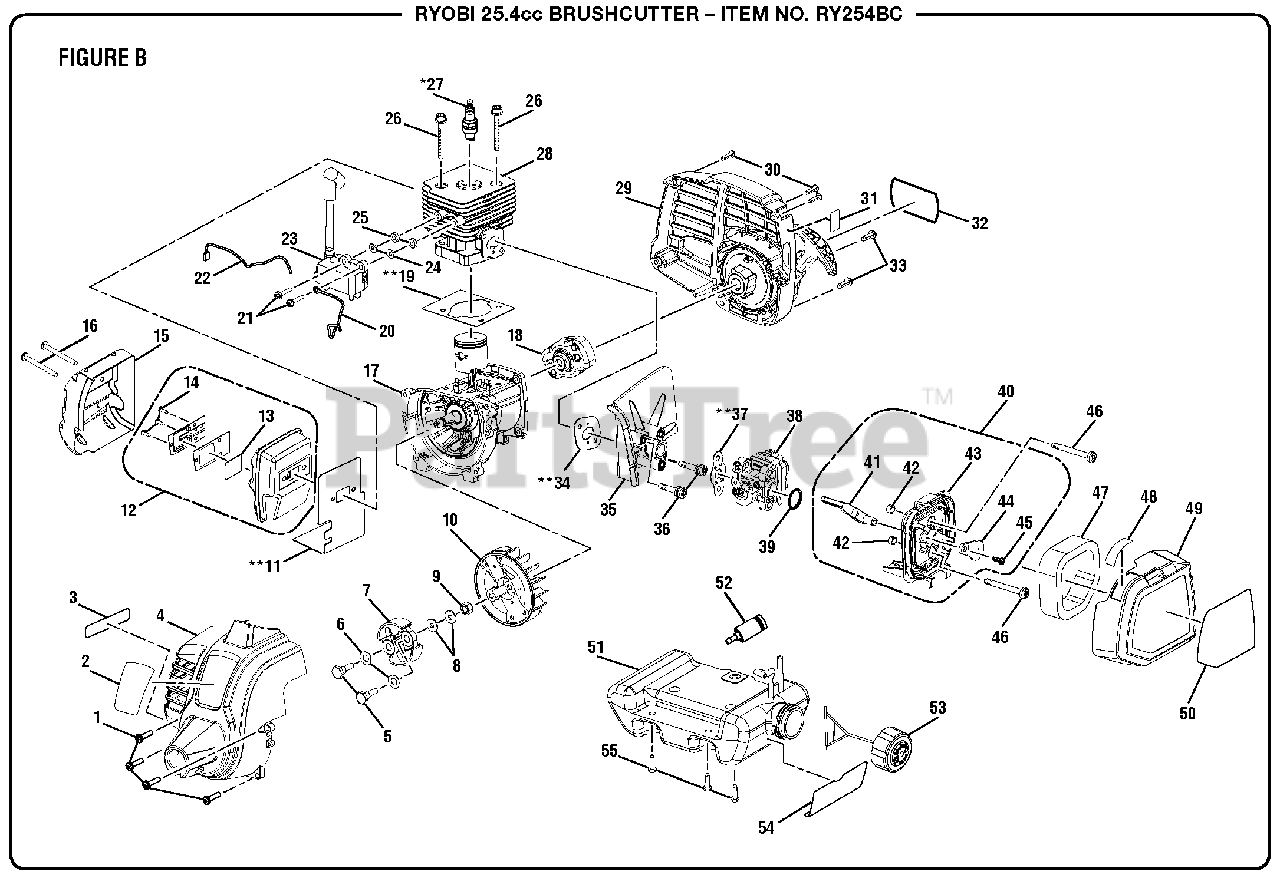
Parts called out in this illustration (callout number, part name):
1	Screw w/Washer (M5 x 20 mm, T20 Torx Pan Hd.)
2	Logo Label (Front)
3	Combustion Warning Label
4	Front Housing Assembly
5	Clutch Shoulder Bolt (M6 x 22.5 mm, Hex Hd.)
6	Curved Washer
7	Clutch Assembly
8	Washer (ID6 x OD15 x 1.2t)
9	Flywheel Nut
11	Muffler Gasket
12	Muffler Assembly
13	Screen
14	Screw (6-20 x 1/4 in., T20 Torx Pan Hd.)
15	Heat Shield
16	Screw (M5 x 50 mm, T25 Torx Pan Hd.)
17	Crankcase Assembly
18	Starter Cup
19	Gasket
20	Lead Wire (Red)
21	Screw w/Washer (M4 x 19 mm, T20 Torx Pan Hd. S.T.)
22	Lead Wire (Black)
23	Coil Boot Assembly
24	Washer (ID4.2 x OD10 x 1t)
25	Spacer (Phenolic)
26	Screw (M5 x 22 mm, Soc. Hd.)
27	Spark Plug (Champion RCJ4)
29	Rear Housing and Starter Assembly
30	Screw (M4 x 18 mm, T20 Torx Pan Hd. S.T.)
31	Primer Bulb Location Label
32	Logo Label (Rear)
33	Cap Screw w/Washer (M5 x 16 mm, T25 Torx Soc. Hd.)
34	Insulator Gasket
35	Heat Dam Insulator
36	Screw (M5 x 27 mm, T25 Torx Pan Hd. S.T.)
37	Gasket
38	Carburetor Assembly
39	Carburetor O-Ring
40	Airbox Base Assembly
41	Choke Lever
42	Compression Limiters
43	Air Box Base
44	Choke Plate
45	Screw (M4 x 12 mm, T20 Torx Pan Hd. S.T.)
46	Screw (M5 x 44 mm, T20 Torx Pan Hd.)
47	Air Filter
48	Choke Position Label
49	Airbox Cover
50	Starting Instructions Label
51	Fuel Tank and Cap Assembly
52	Fuel Filter
53	Fuel Cap Assembly
54	Fuel Mixture Label
55	Shoulder Screw (M4 x 14 mm, T25 Torx Truss Hd. S.T.)
